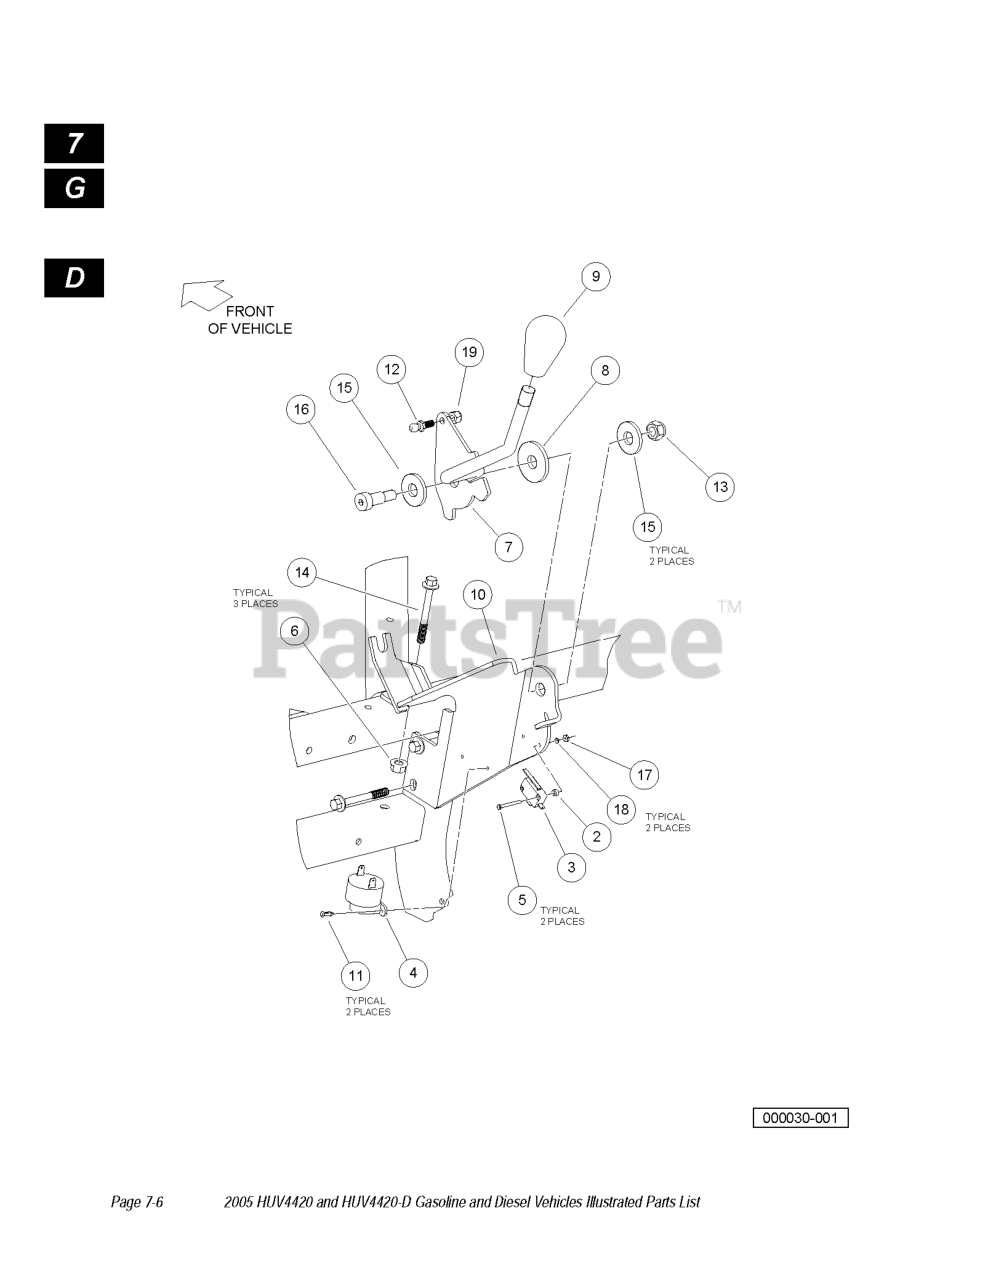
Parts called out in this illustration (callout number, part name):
3	SWITCH,LIMIT
4	BUZZER, 9-48 VDC REVERSE
5	SCREW, #4-40 X 1.125 HX HD MCH
6	NUT FLG, M8 X 1.25 MECH DEF
8	BUSHING, FNR
9	KNOB, FNR
12	STUD, BALL, .346 DIA
13	LOCKNUT-M10X1.5
14	BOLT FLG, M8X1.25X65
15	WASHER, M12 HARD REGULAR
16	SHOULDER BOLT,M12 X 20 M10 THD
17	NUT HEX MACHINE
18	LOCKWASH, # 4 HELICAL SPLIT
19	LOCKNUT, 1/4-28 NYLON INSERT
